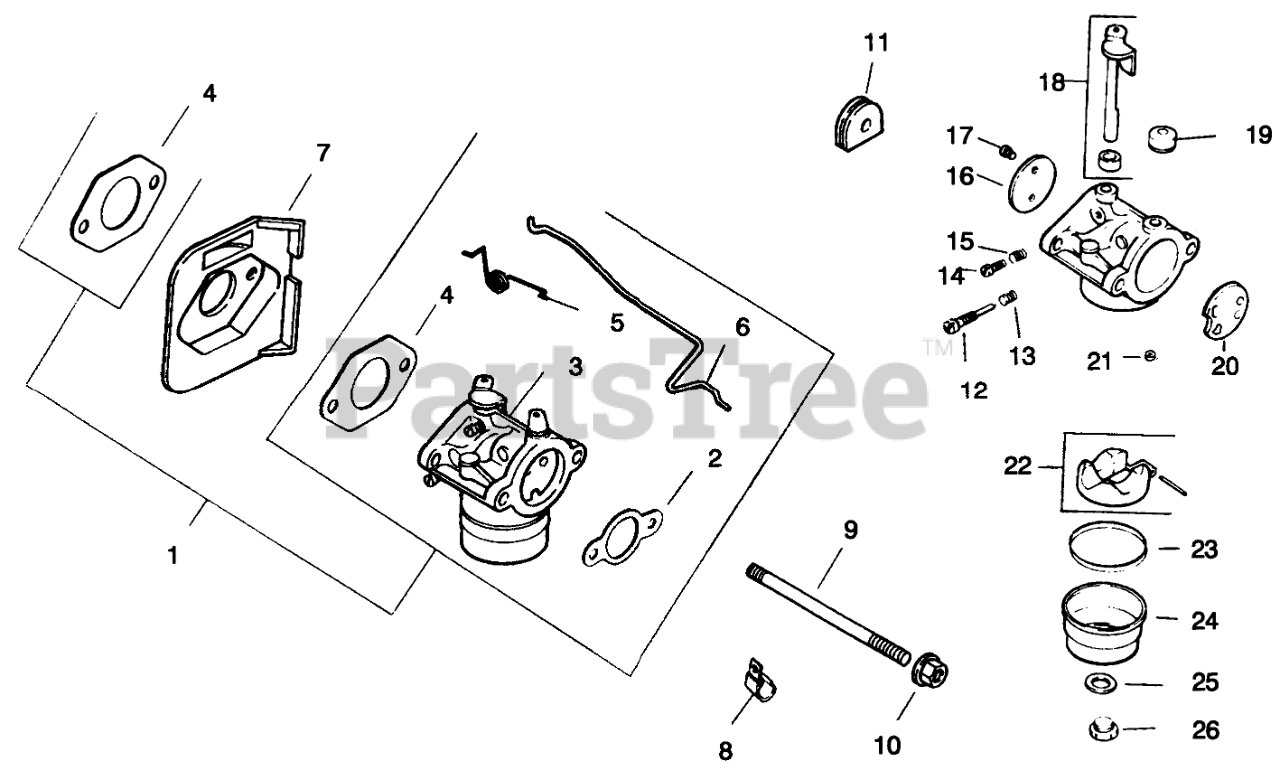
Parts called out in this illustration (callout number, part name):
1	Kit-Carburetor (Incl Ref. #2-6)
2	Gasket-Air Cleaner
3	Carburetor Assembly (Incl Ref. #12-26)
4	Gasket-Carburetor
5	Spring Choke
6	Linkage Choke
7	Deflector-Heat
8	Clamp
9	Stud
11	Grommet
12	Needle-Idle
13	Spring-Idle
14	Screw-Idle
15	Spring-Idle
16	Plate-Choke
17	Screw
18	Shaft-w/Lever & Seal
19	Cap-Choke Lever
20	Plate-Choke
21	Jet-Main
22	Kit-Float
23	Gasket-Bowl
24	Bowl-Fuel
25	Gasket-Bowl
26	Screw-Bowl
